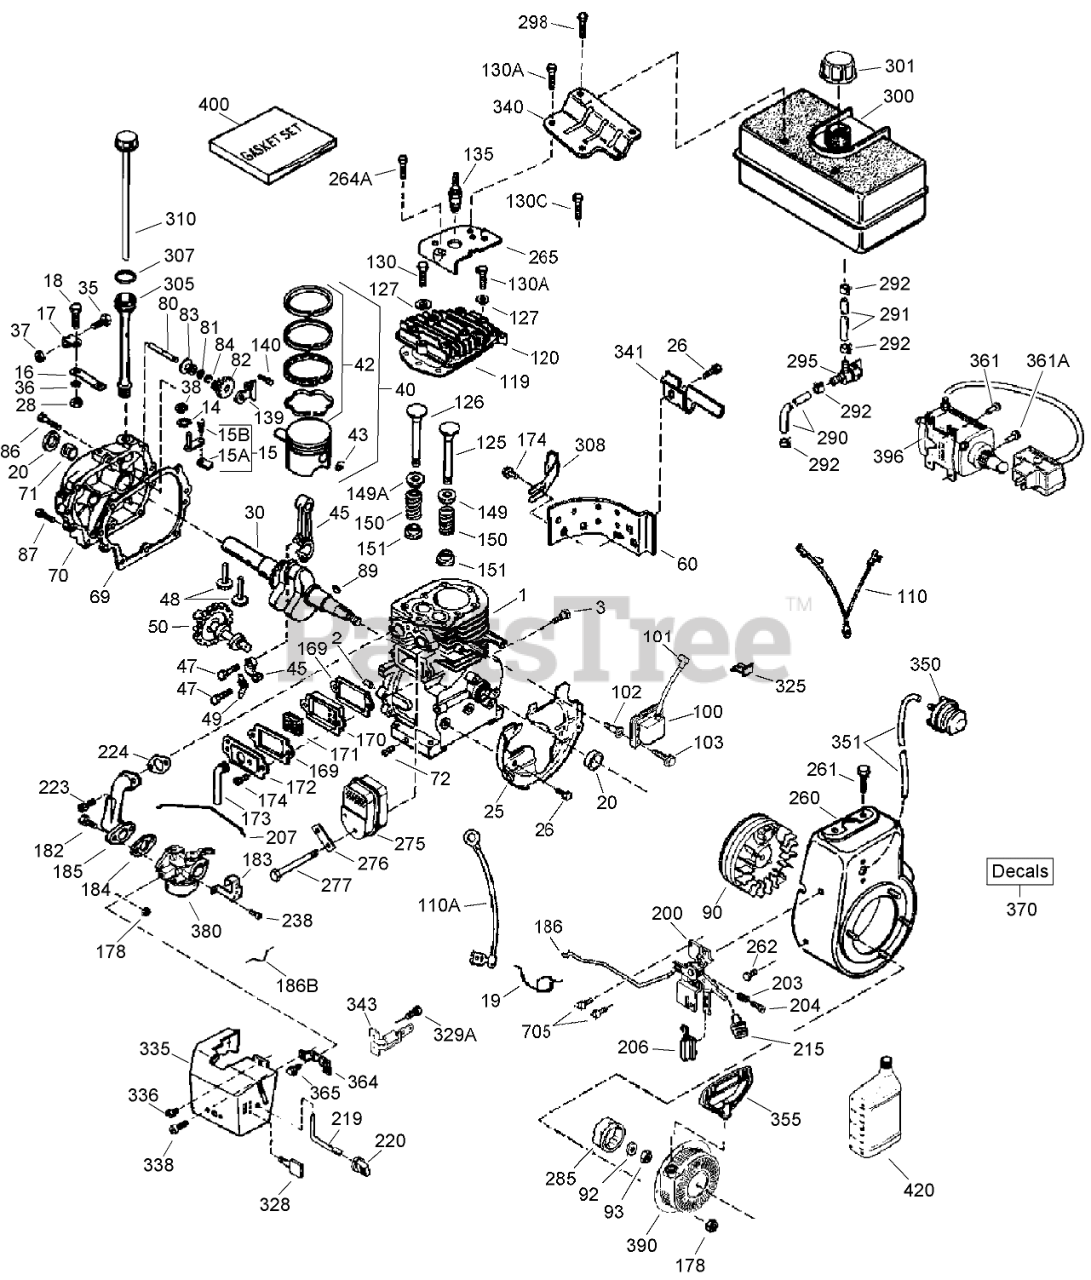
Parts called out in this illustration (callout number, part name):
1	Cylinder ASM (Includes 2, 20, 72, 72A) (3-1/8 Bore)
2	Pin-Dowel
3	Screw (1/4-20x1/2)
14	Washer-Flat
15	Rod-Governor (Includes 15A, 15B)
15A	Yoke-Governor
15B	Screw (6-40x5/16)
16	Lever-Governor
17	Clamp-Lever, Governor
18	Screw (T-15, 8-32x7/16)
19	Spring-Throttle
20	Seal-Oil
25	Baffle-Housing, Blower
26	Screw (1/4-20x19/32)
28	Nut-Lock
30	Crankshaft
35	Screw
36	Washer-Lock
37	Nut-Lock
38	Ring-Retaining
40	Piston-Pin and Ring Set (STD)
40	Piston- Pin and Ring Set (.010 O S)
42	Ring Set (STD)
42	Ring Set (.010 O S)
43	Ring-Retaining, Piston Pin
45	Connecting Rod ASM (Includes 47, 49)
47	Bolt-Rod, Connecting
48	Lifter-Valve
49	Dipper-Oil
50	Camshaft (MCR)
60	Extension-Housing, Blower
69	Gasket-Cover, Cylinder
70	Cylinder Cover (Includes 71, 75, 80-84)
71	Bushing-Crankshaft
72	Plug-Drain, Oil (SQH 1/4-18)
80	Shaft-Governor
81	Washer
82	Governor Gear ASM (Includes 81)
83	Spool-Governor
84	Ring-Retaining
86	Screw (1/4-20x1-3/16)
87	Screw (1/4-20x1-11/16)
89	Key-Flywheel
90	Flywheel (W/Ring Gear)
92	Washer-Belleville
93	Nut-Flywheel
100	Ignition-Solid State (Includes 101)
101	Cover-Spark Plug
102	Stud-Mounting, Solid State
103	Screw (T-15, 10-24 x 15/16)
110	Wire-Ground
110A	Wire-Ground
119	Gasket-Head, Cylinder
120	Head-Cylinder
125	Valve-Exhaust (Std.)(Includes 151)
125	Valve-Exhaust (1/32 OS) (Includes 151)
126	Valve-Intake (Std) (Includes 151)
127	Washer-Flat
130	Screw (5/16-18x1-1/2)
130A	Screw (5/16-18x1-25/32)
130C	Screw (5/16-18x39/64)
135	Spark Plug-Resistor (R J19 L M) (also available in Packaged Part #740081)
139	Bracket-Gear, Governor
140	Screw (10-24x1/2)
149	Cap-Spring, Valve
149A	Cap-Spring, Valve
150	Spring-Valve
151	Keeper-Spring, Valve
169	Gasket-Cover, Valve
170	Body-Breather
171	Element-Breather
